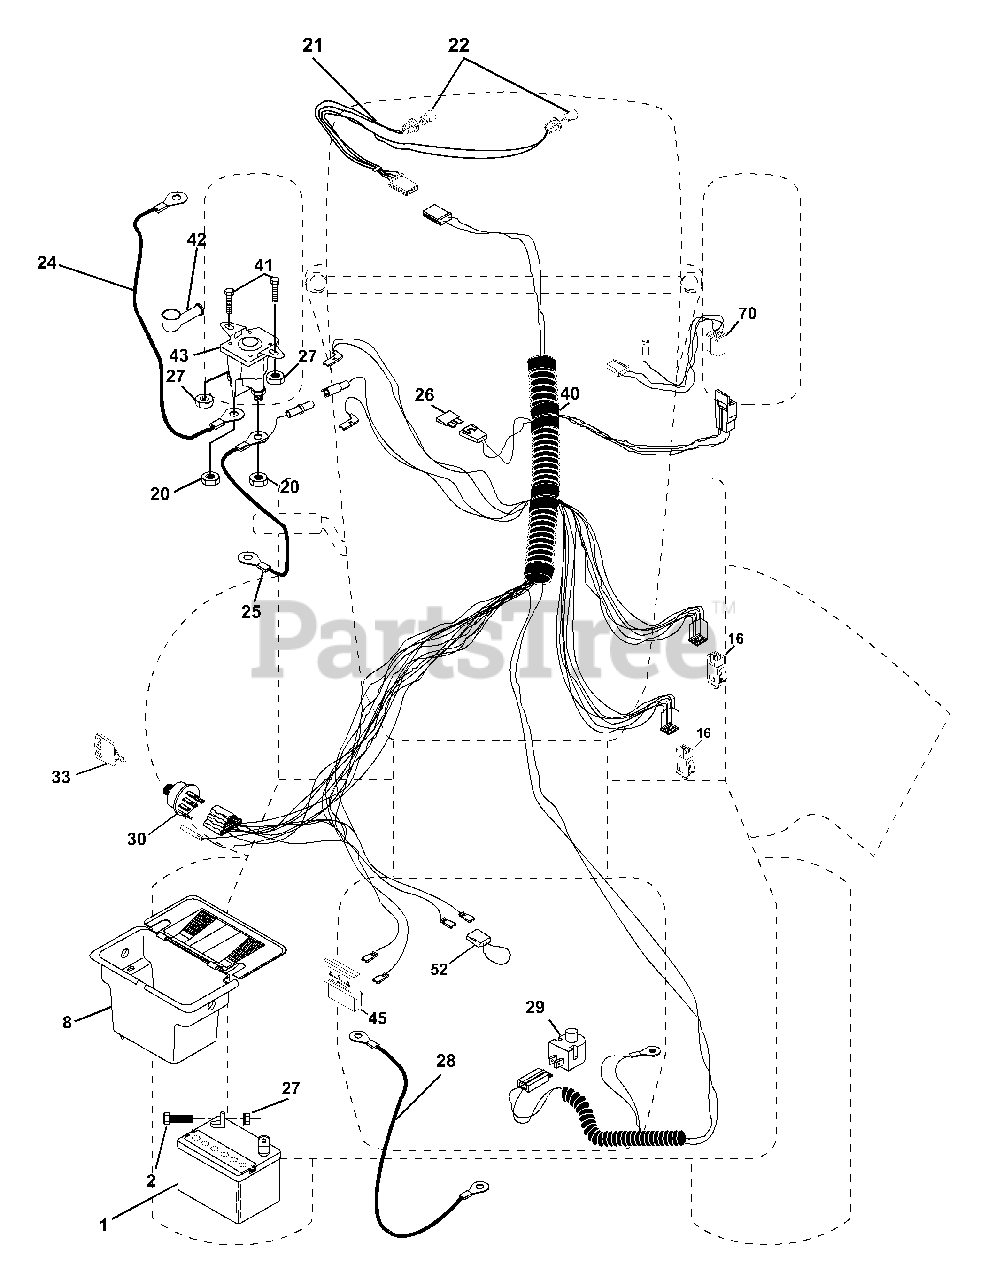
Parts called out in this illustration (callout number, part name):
1	Battery 12 Volt 25 AMP
2	Bolt Hex Hd 1/4-20unc X 3/4
8	Case Battery Mech Hinge
16	Switch Interlock Push-In
20	Nut Jam Hex 1/4-20 Unc
21	Harness Asm Light W/4152j
22	Bulb Light #1156
24	Cable Battery 6 Ga 11" red
25	Cable Battery 6 Ga 44" red w/16 wire
26	Fuse 15 AMP
27	Nut Keps Hex 1/4-20 Unc
28	Cable Ground 6 Ga 12" black
29	Switch Plunger Nc Gray
30	Switch Ign Delta
33	Key Ign Molded Generic
40	Harness Ign.
41	Bolt Blk Fin Hex 1/4 - 20 x 1/2
42	Cover Terminal Red
43	Solenoid
45	Ammeter Rectangular 6 Amps
52	Protection Wire Loop
70	Harness, Eng. B&S
